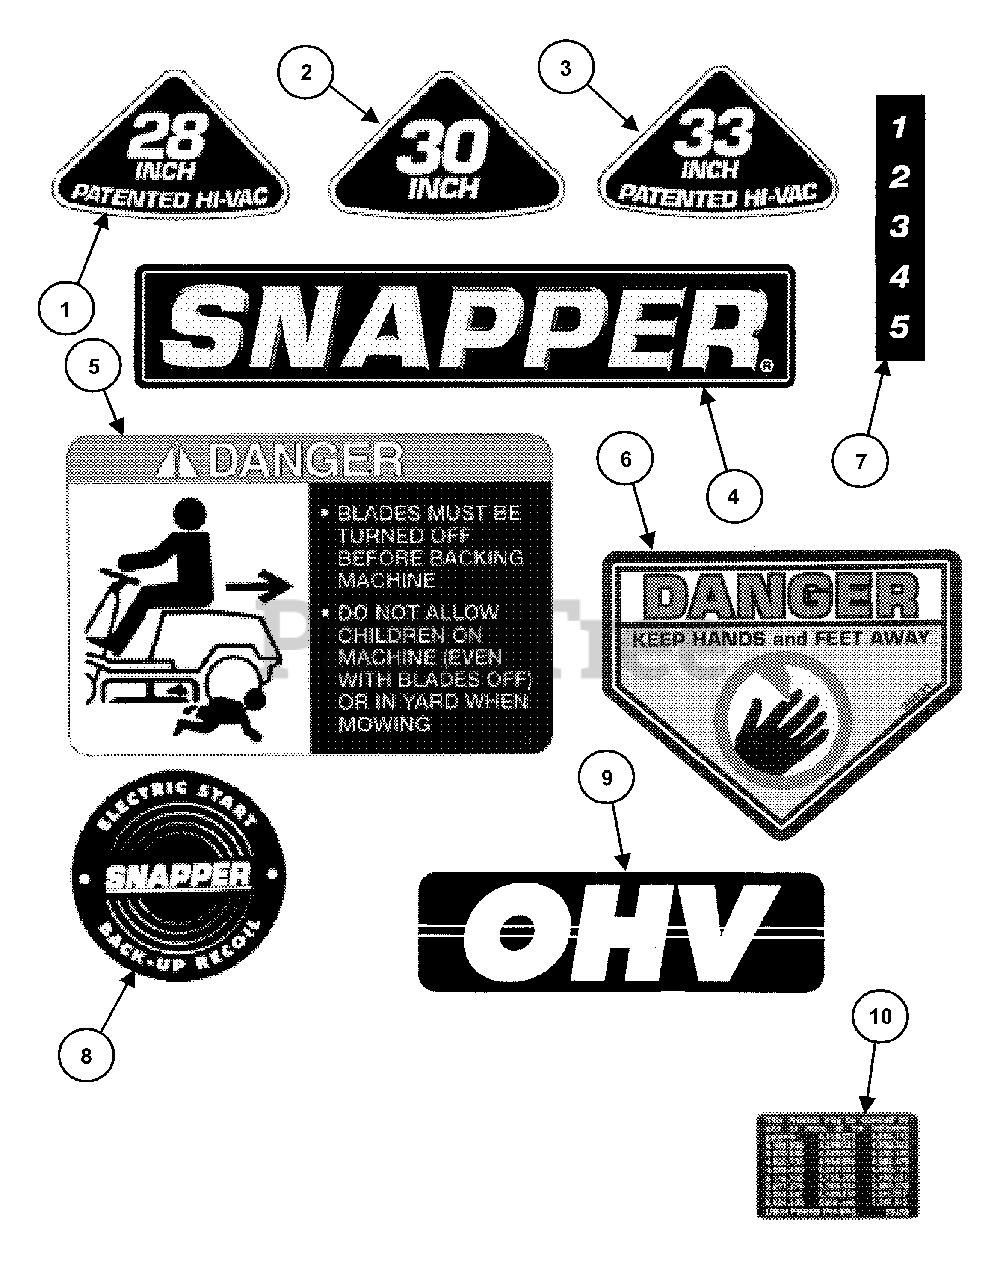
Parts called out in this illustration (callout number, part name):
1	DECAL, 28 Inch
2	DECAL, 30 Inch
3	DECAL, 33 Inch
4	DECAL, Snapper
5	DECAL, No Mow in Reverse
6	DECAL, Danger (CPSC)
7	DECAL, Height Cut
8	DECAL, Back-up Recoil
9	DECAL, OHV
10	DECAL, Patent Numbers
